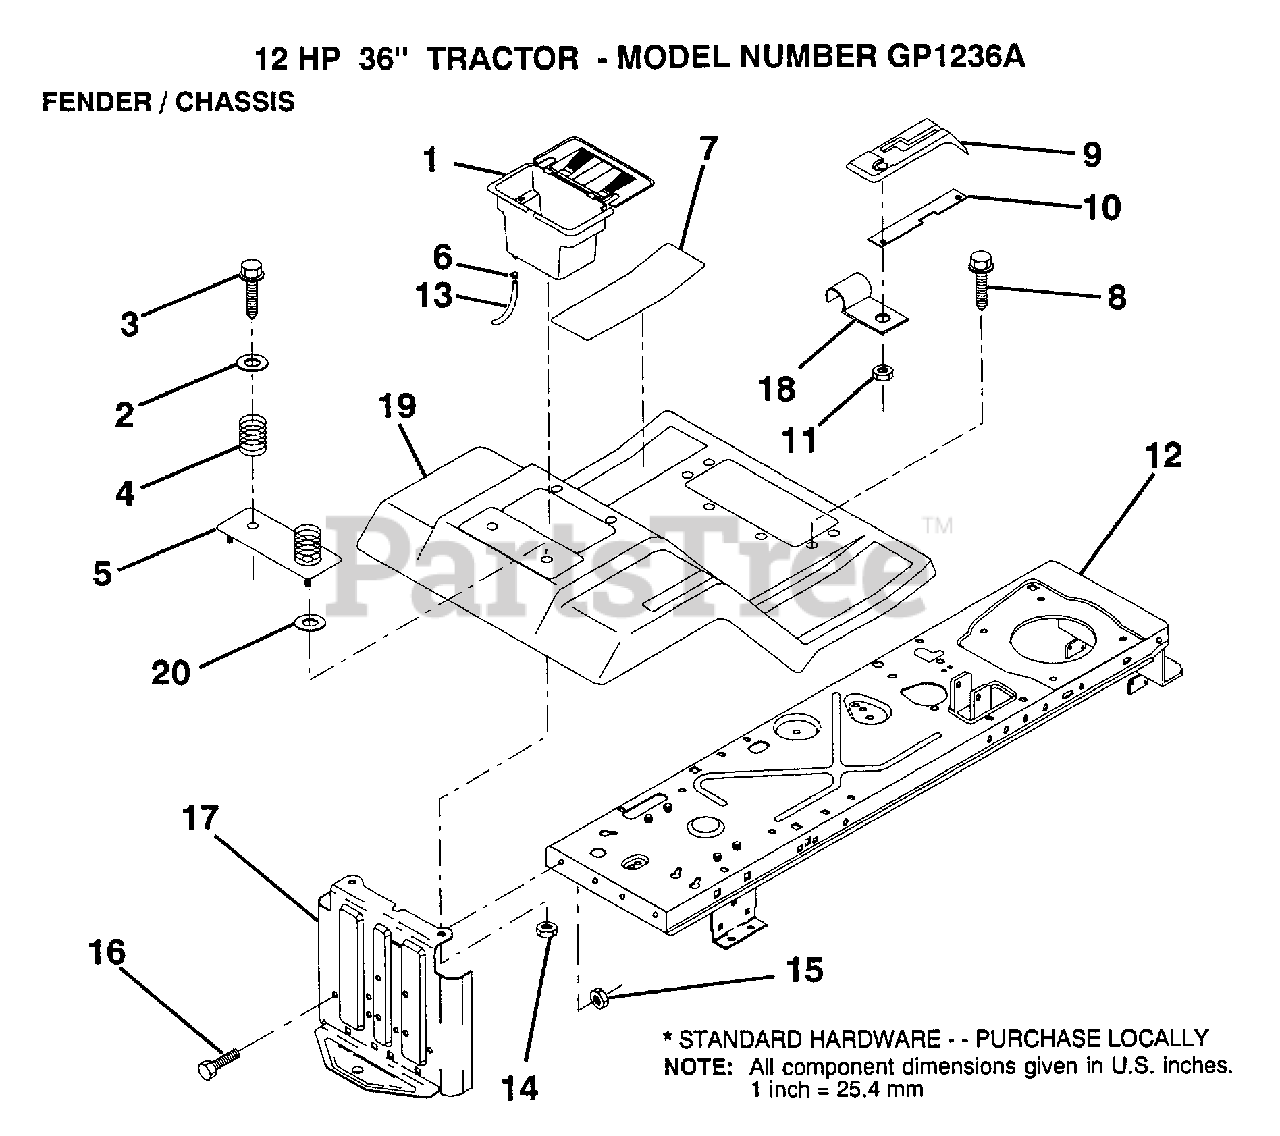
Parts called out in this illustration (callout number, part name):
2	WASHER
3	SCREW
4	SPRING COMPRESSIO
5	"PLATE, BATTERY"
6	HOSE CLAMP T
7	PAD FOOTREST
8	SCREW
11	NUT
14	NUT
16	BOLT
17	DRAWBAR
18	"CLIP,INSULATOR"
